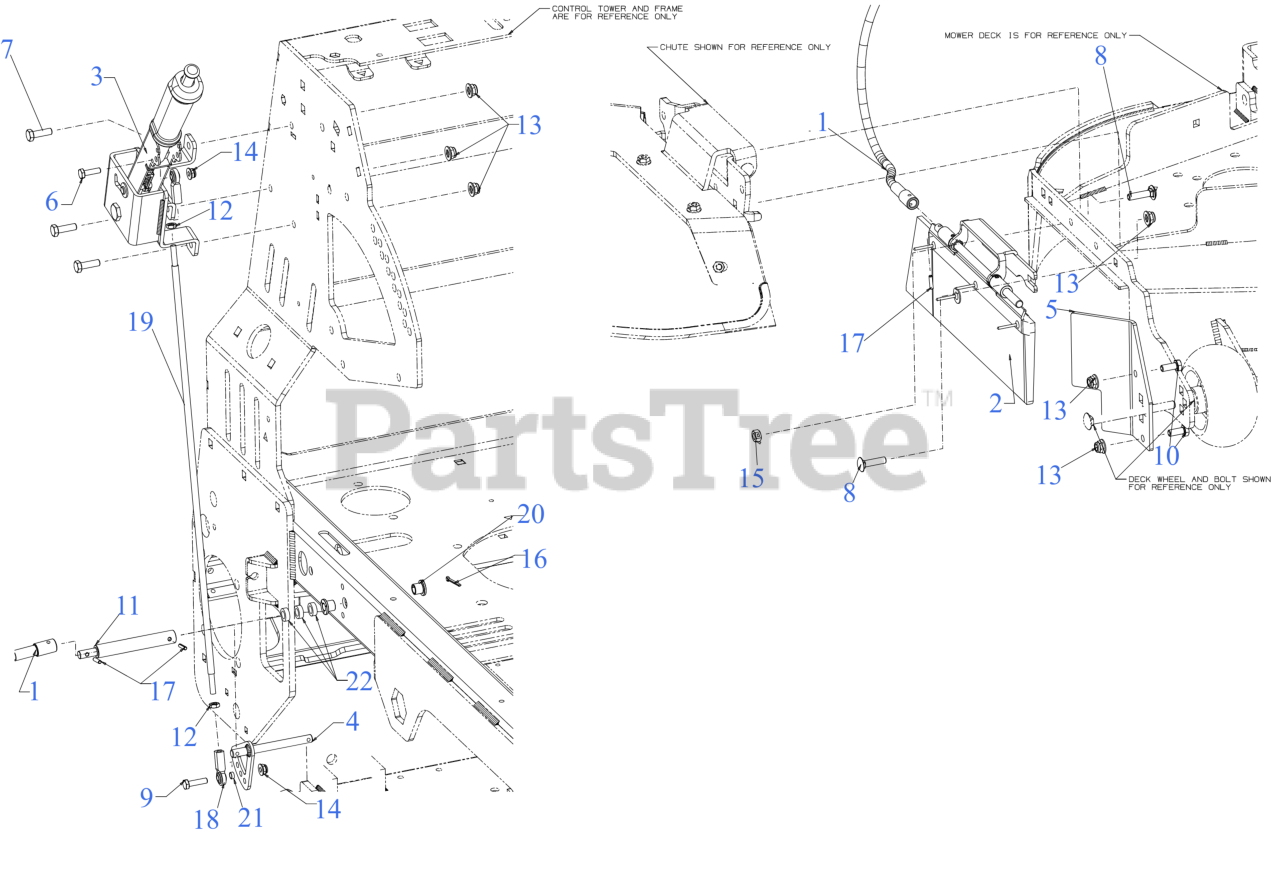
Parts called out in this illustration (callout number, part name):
1	DISCHARGE DOOR CONTROL
2	DISCHARGE DOOR ASSEMBLY
3	DOOR HANDLE
4	DOOR SHAFT
5	BRACKET
6	HEX SCREW 1/4-20 x .875 GR5
7	SCREW 5/16-18 x 1.0 GR5
8	CARRIAGE BOLT 5/16-18 x 1.25
9	SCREW 1/4-20 X1.00 GR5
10	SCREW 5/16-18 x .75 GR5
11	ADAPTER SHAFT 4.25"
12	HEX JAM NUT 1/4-28
13	FLANGE LOCK NUT 5/16-18
14	FLANGE LOCK NUT
16	COTTER PIN
17	ROLL PIN 5/32" x .688"
18	END ROD (RH)
20	FLANGE BEARING
22	SPACER-.380 ID x .625 OD x .227
